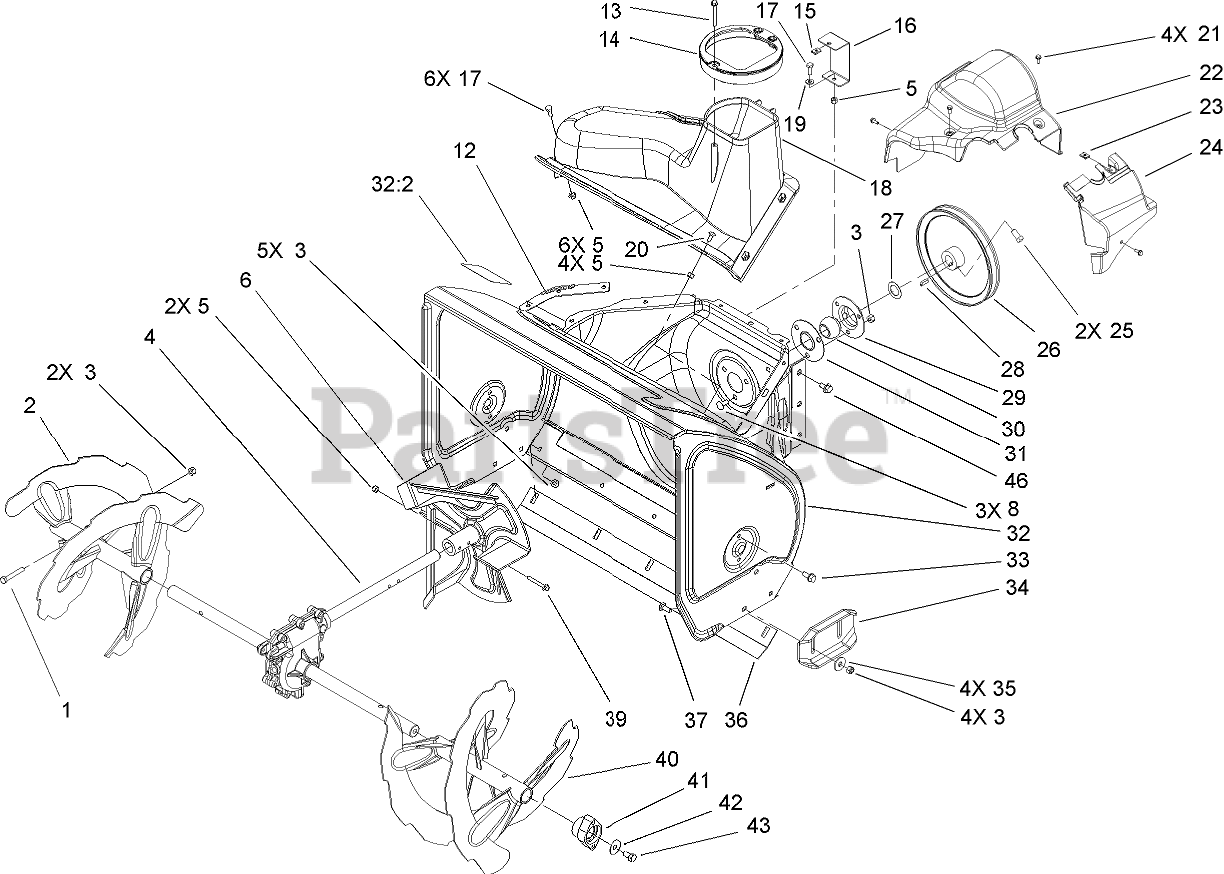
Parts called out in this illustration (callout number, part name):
1	SCREW-HH
2	RH AUGER ASM
3	NUT-LOCK, NI
4	26INCH AUGER GEARCASE ASM
5	NUT-LOCK, NI
6	IMPELLER ASM
8	SCREW-CARR
12	SEAL-FLANGE, COVER
13	SCREW-PLASTITE
14	GUIDE-CHUTE
15	NUT-SPEED, U-TYPE
16	BRACKET-COVER, CLIP NUT
17	SCREW-HH
18	COVER
19	WASHER-FLAT
20	BOLT-CARR
21	SCREW-HWH
22	COVER-BELT
23	NUT-SPEED
24	COVER-EXTENSION, BELT
25	SCREW-SET, SQH
26	PULLEY-IMPELLER
27	WASHER-THRUST
28	KEY-WOODRUFF
29	FLANGE-CUP, BEARING
30	BEARING-BALL
31	FLANGE-CUP, BEARING
32	HOUSING-AUGER, 26 INCH
32:2	DECAL-WARNING, AUGER
33	SCREW-HWHTF
35	WASHER
36	SCRAPER-FIXED
37	SCREW-CARR
39	SCREW-HHF
40	LH AUGER ASM
41	BEARING-AUGER
42	WASHER
43	SCREW-HH
46	SCREW-HWHTF
